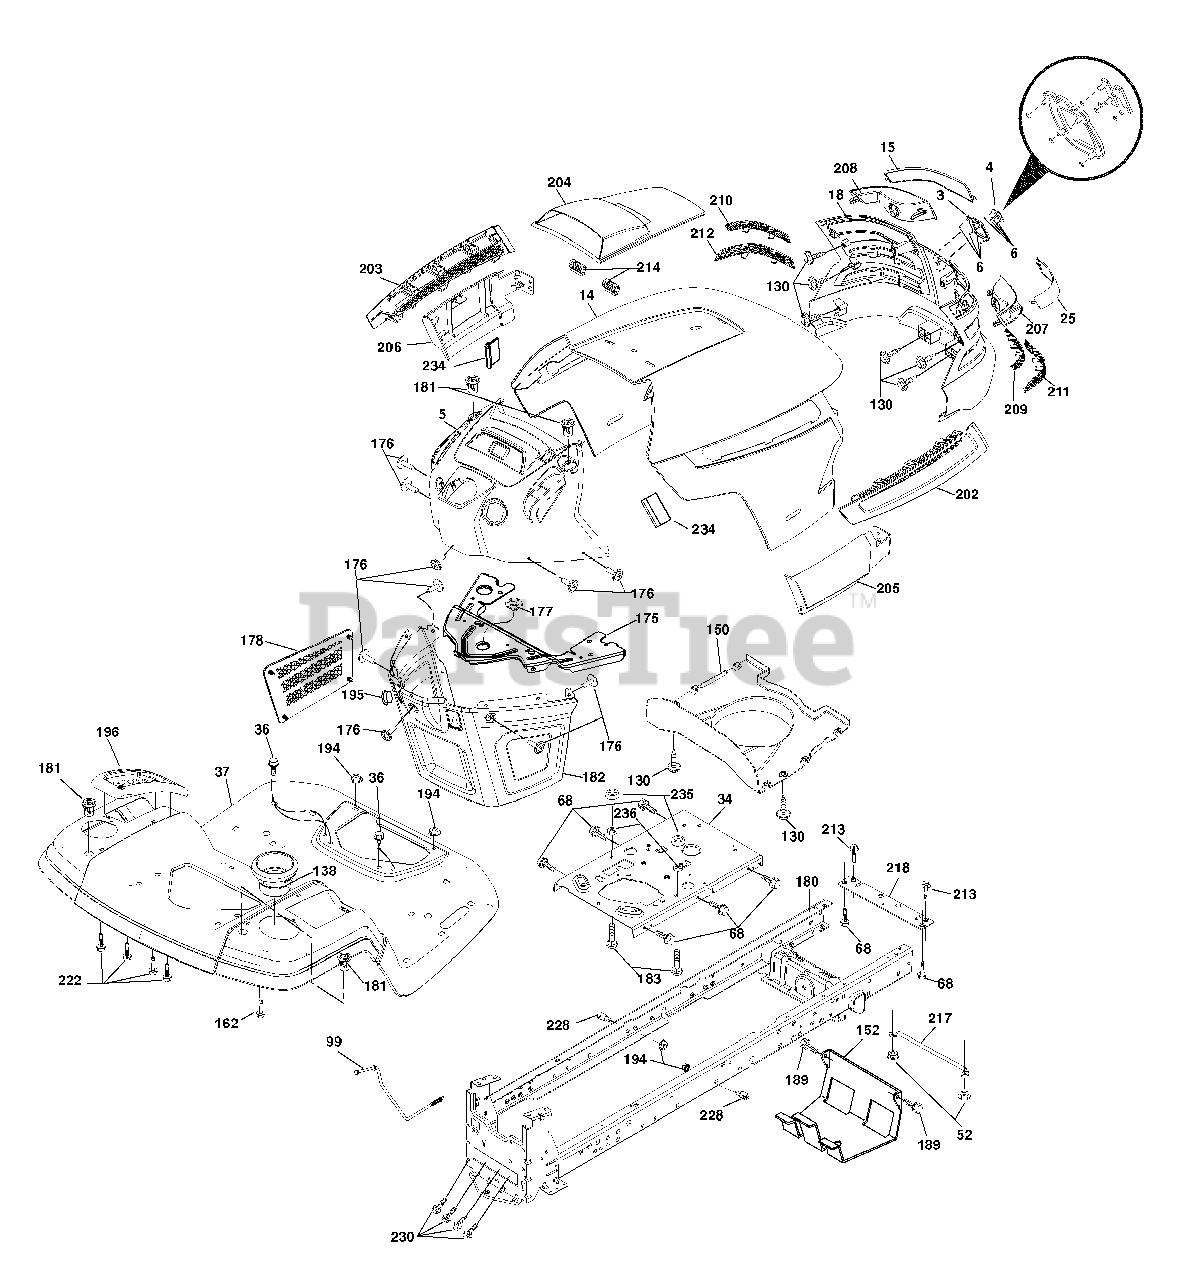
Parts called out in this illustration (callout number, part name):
3	Logo Crown
4	Logo
14	Hood
18	Grille/Lens Asm.
34	Plate Engine
36	Screw 5/16-18 x 3/4
37	Fender
52	Nut Lock 5/16-18
68	Screw Thdrol 5/16-18 x 1/2
99	Rod Asm Bypass
130	Screw 10 x 3/4 Single Lead-Hex
138	Cupholder
152	Shield Browning
175	Crossmember
176	Screw 10-24 x 5/8
177	Bushing Steering
178	Cargo Net Asm.
180	Chassis
181	Bushing Mtg. Fender Crgo
182	Dash Lower
183	Bolt Fin Hex 5/16-18 unc x 1-1/4
189	Screw 5/16-18 x 3/4
194	Nut Lock Hex Flange 5/16-18
195	Plug Hole Dash Lower
196	Console Asm. Deck Lift
202	Vent Side Hood RH
203	Vent Side Hood LH
204	Vent Top Hood
205	Skirt Hood Side RH
206	Skirt Hood Side LH
209	Insert Hex Top RH
210	Insert Hex Top Lh
211	Insert Hex Bottom RH
212	Insert Hex Bottom LH
213	Bolt 5/16-18 x 3/4
214	Clip Retainer Tinner
217	Rod Pivot
218	X-Piece Hood Stop
222	Screw Thdrol 1/4-20 x 5/8
228	Stud Fastner
230	Bolt Shoulder 5/16-18
234	Bumper Hood
235	Spacer Fender
236	Nut Lock 5/16-18 UNC
